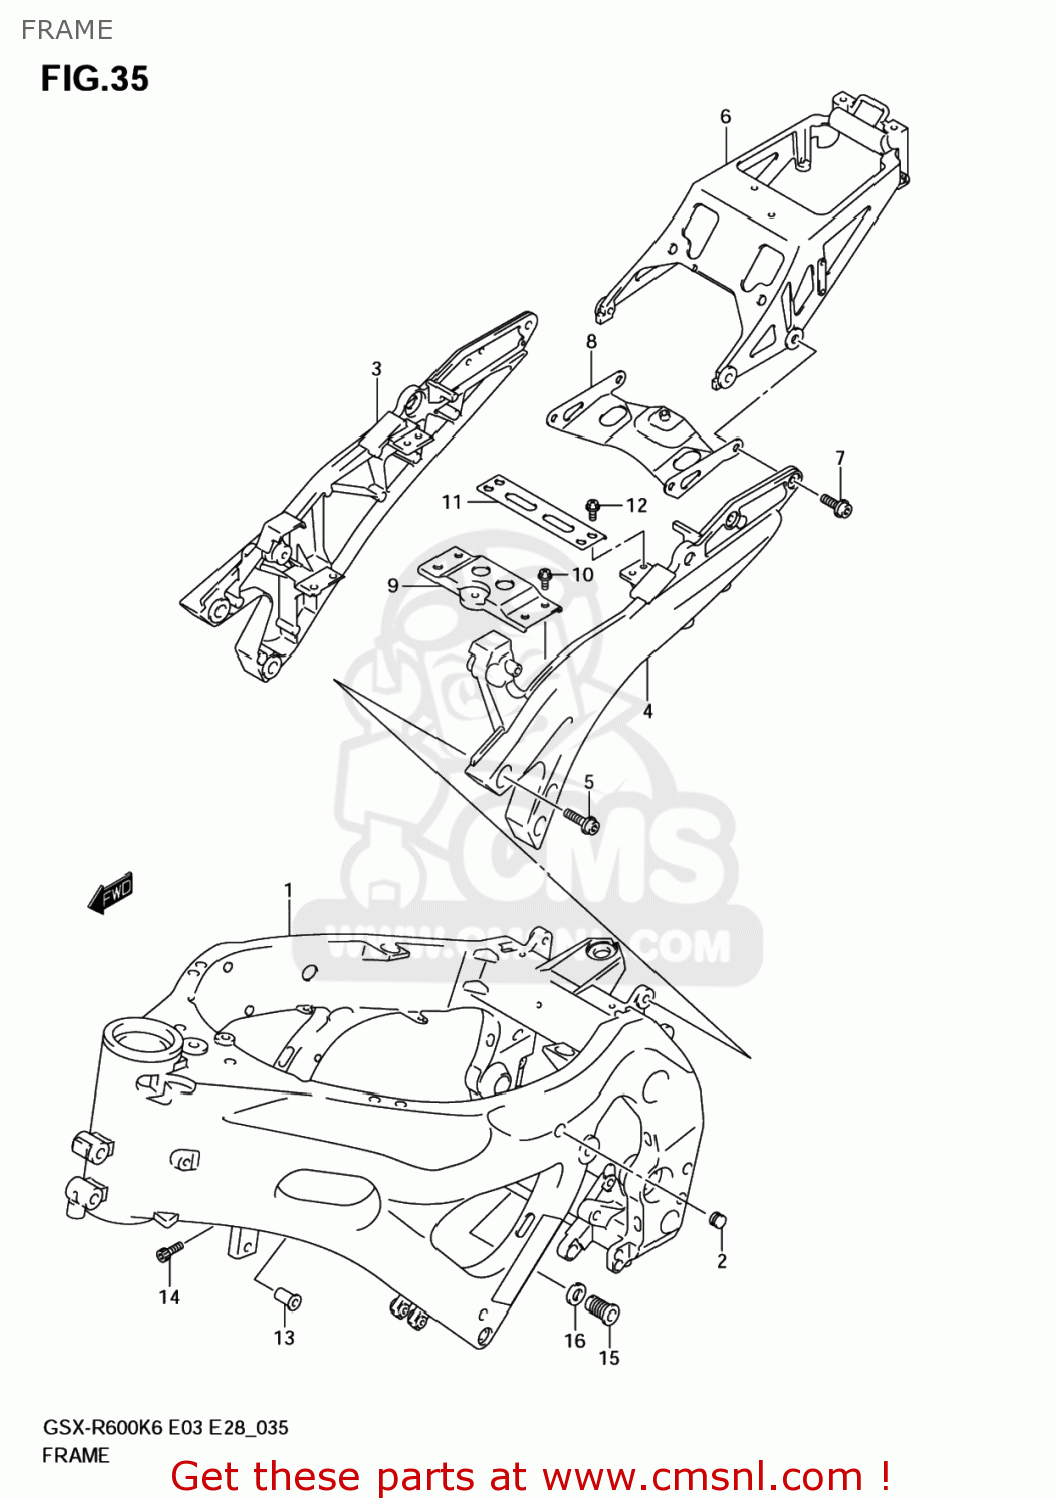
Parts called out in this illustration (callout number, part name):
1	FRAME(BLACK)
2	PLUG,TANK RAIL
3	RAIL,SEAT,R(BLACK)
4	RAIL,SEAT,L(BLACK)
5	BOLT,SEAT RAIL
6	BRACKET,PILLION SEAT
7	BOLT
8	BRIDGE,SEAT RAIL RR
9	BRIDGE,SEAT RAIL FR
10	BOLT,OIL GUTTE
11	BRIDGE,SEAT RAIL UPR
12	BOLT,OIL GUTTE
13	SPACER,ENGINE MOUNTING
14	BOLT
15	BOLT,CRANK CASE ADJUST
16	NUT,ADJUST BOLT
